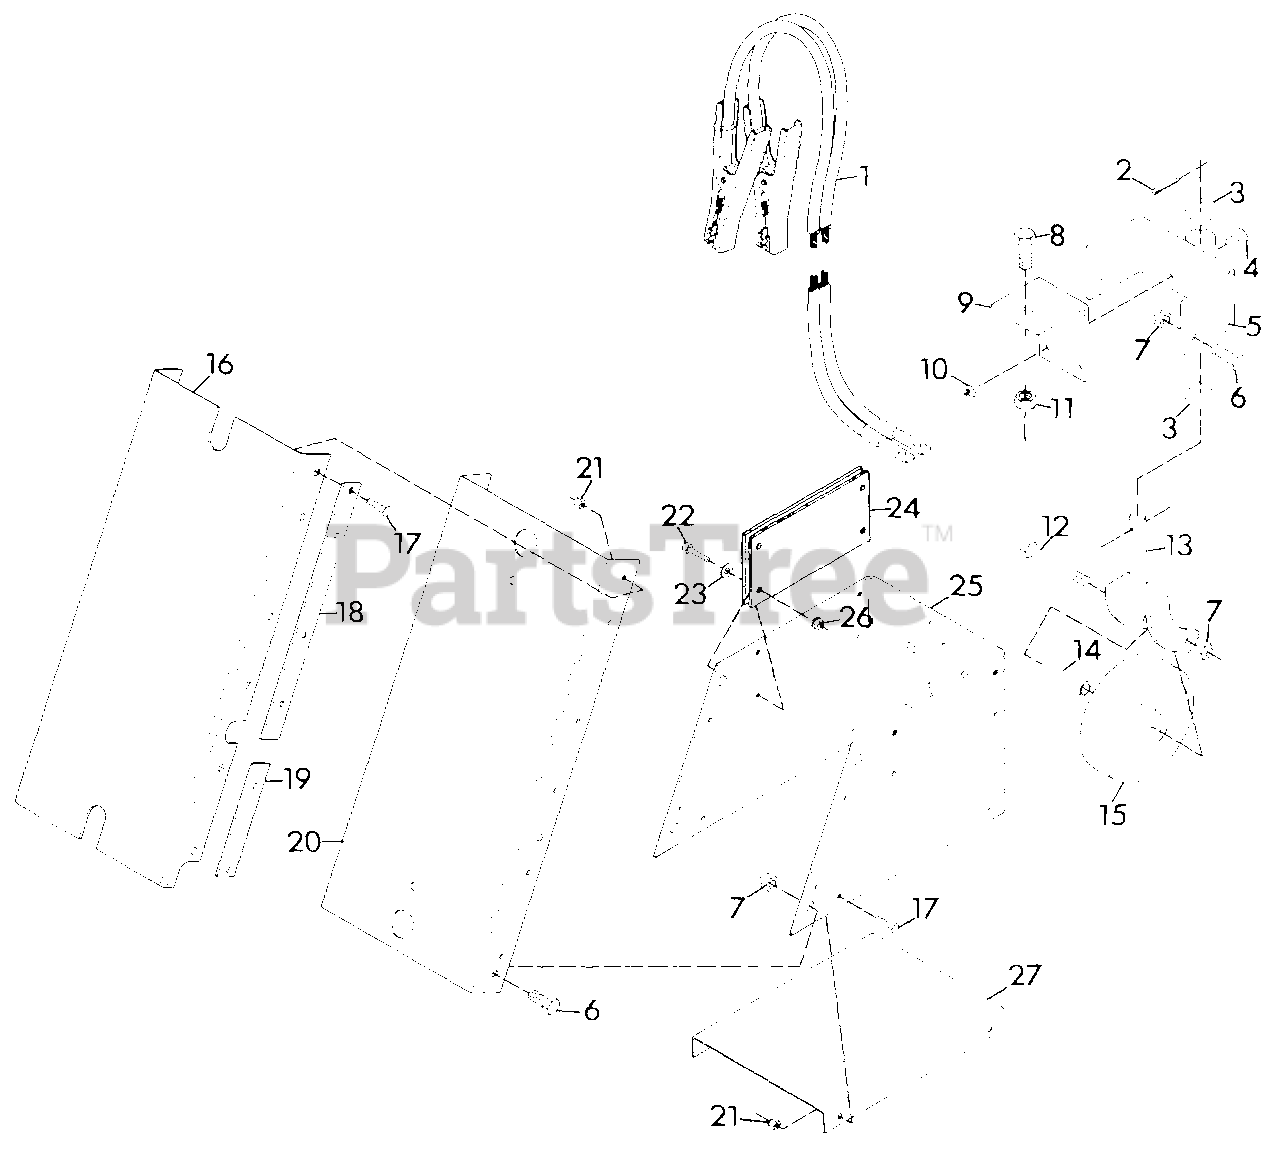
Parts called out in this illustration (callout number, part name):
1	ASSEMBLY, CABLE
2	PIN, COTTER .125X1.25
3	BUSHING, NYLON .76X1.00X.6 FLANGE
4	BOLT, HEX 3/8-16X1.00
5	WELDMENT, CASTER WHEEL SUPPORT
6	BOLT, HEX 1/2-13X1.25
7	NUT, LOCK 1/2-13
8	BOLT, HEX 5/8-11X1.50
9	BRACKET, CASTER FORK MOUNTING
10	NUT, LOCK 3/8-16
11	NUT, LOCK 5/8-11
12	BOLT, HEX 1/2-13X3.75
13	WELDMENT, CASTER FORK
14	BUSHING, .515X.750X2.594
15	WHEEL, CASTER
16	PAD, BUMPER
17	BOLT, HEX 1/4-20X1.00
18	STRIP
19	STRIP
20	BUMPER
21	NUT, LOCK 1/4-20
22	BOLT, 1/4-20X1.0 NYLON
23	WASHER, FRICTION
24	PAD, INSULATOR
25	FRAME, 2-WHEEL PUSHER
26	NUT, NYLON
27	TRAY
